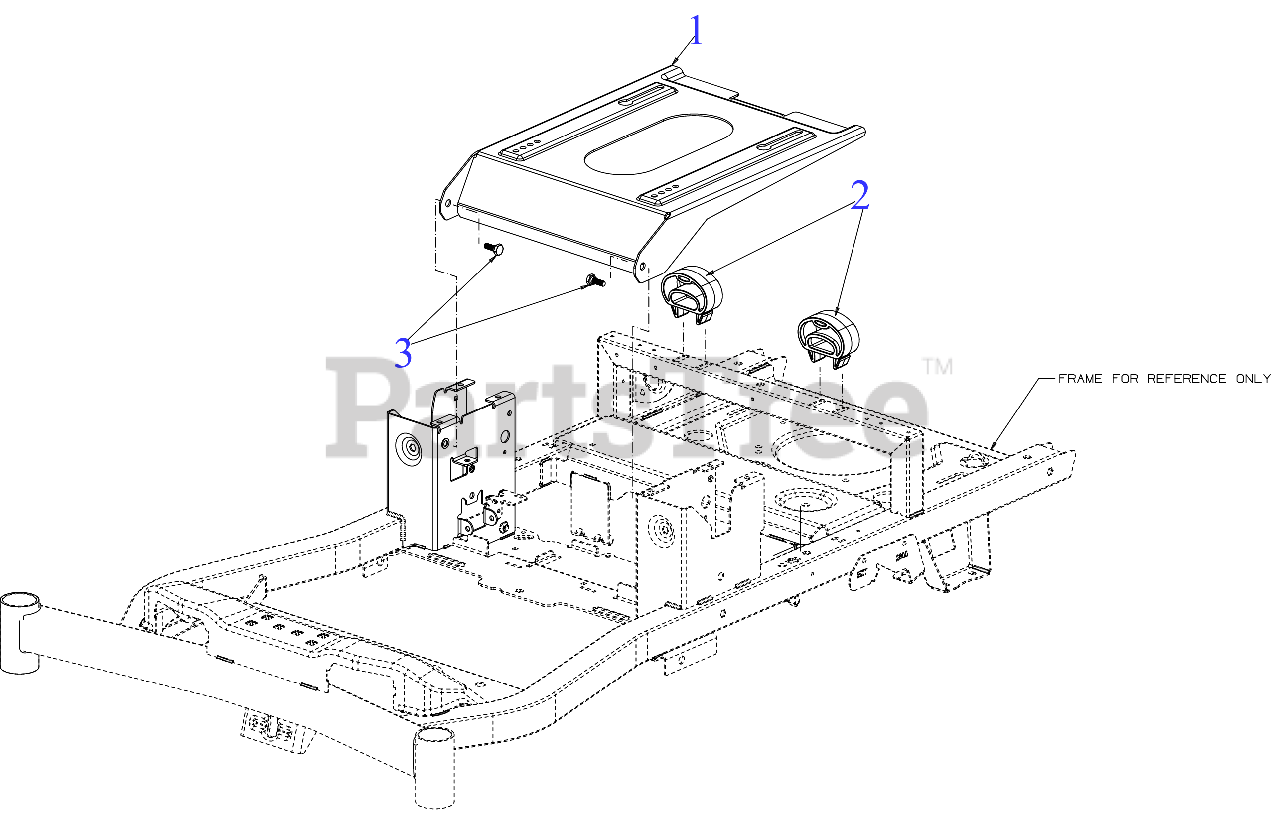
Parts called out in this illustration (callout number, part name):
1	SEAT BASE PLATE
2	POLYMER SEAT SPRING
3	SHOULDER SCREW .44DIAx.18 5/16-18
